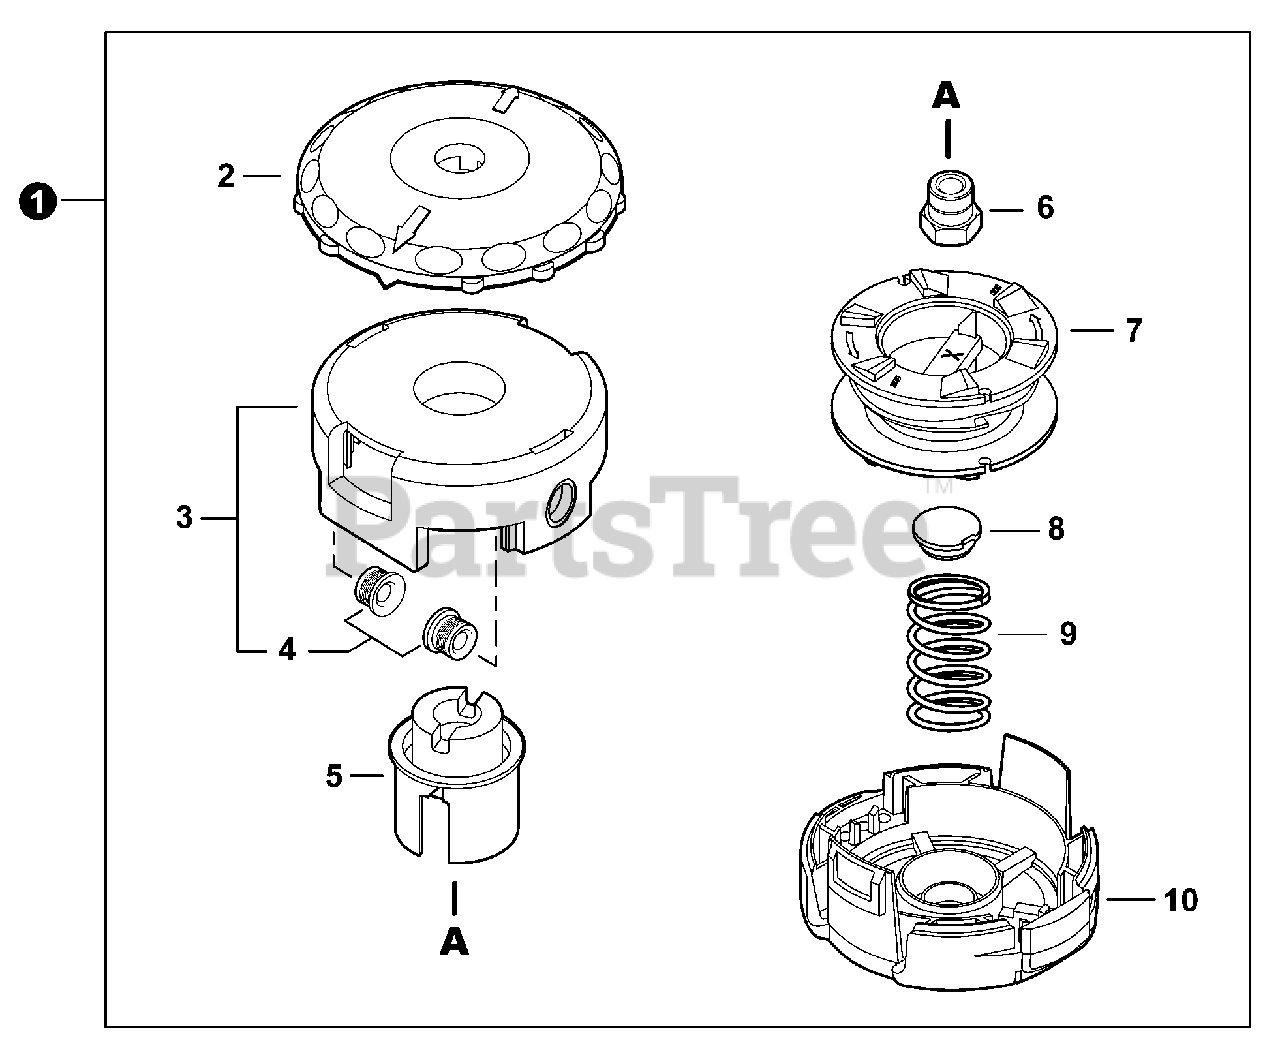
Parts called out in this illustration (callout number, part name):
1	TRIMMER HEAD, SPEED-FEED® 400
3	HOUSING ASSY, SPOOL
5	HUB (LH) BLACK
6	BUSHING M10x1.25 LH GOLD
8	CAP, SPRING
9	SPRING, GOLD
10	COVER, SPOOL
